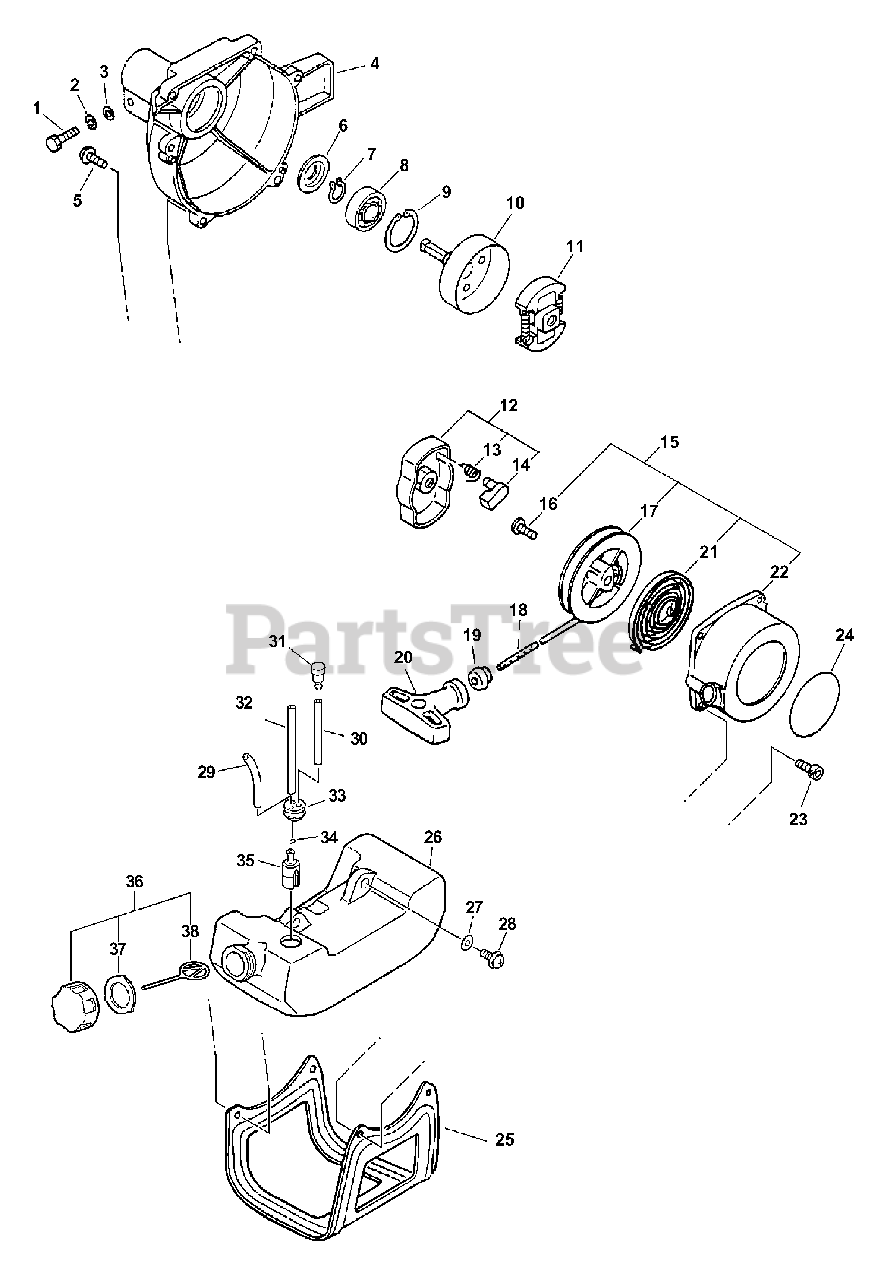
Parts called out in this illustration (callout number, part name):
1	BOLT 5×25
2	WASHER, SPRING 5
3	WASHER, FLAT 5.5×10×0.8
4	CASE, FAN
5	BOLT 4×16
6	STOPPER, PIPE
7	RING, RETAINING - 12
8	BEARING, BALL 6201-ZZ
9	RING, SNAP Ø32
10	DRUM, CLUTCH
11	CLUTCH ASSY
12	PAWL ASSY, STARTER
13	SPRING, RETURN
14	PAWL, STARTER - BLACK
15	STARTER ASSY, RECOIL
16	SCREW
17	REEL, ROPE
18	ROPE, STARTER 3.0×1000
19	GUIDE, ROPE
20	GRIP, STARTER
21	SPRING, RECOIL
22	CASE, RECOIL STARTER
23	BOLT 4×16
24	LABEL, ECHO
25	GUARD, FUEL TANK
26	TANK, FUEL
27	WASHER 5.5×12×0.8
28	SCREW 5×16
29	PIPE, FUEL RETURN 3×6×90 MM CLEAR
30	PIPE, FUEL 3x-5x-70 BLACK
31	VENT ASSY
32	PIPE, FUEL 3x-5x-180
33	GROMMET, FUEL
34	CLIP 6 MM
35	FILTER, FUEL
36	CAP ASSY, FUEL
37	GASKET, FUEL CAP
38	CONNECTOR, CAP
